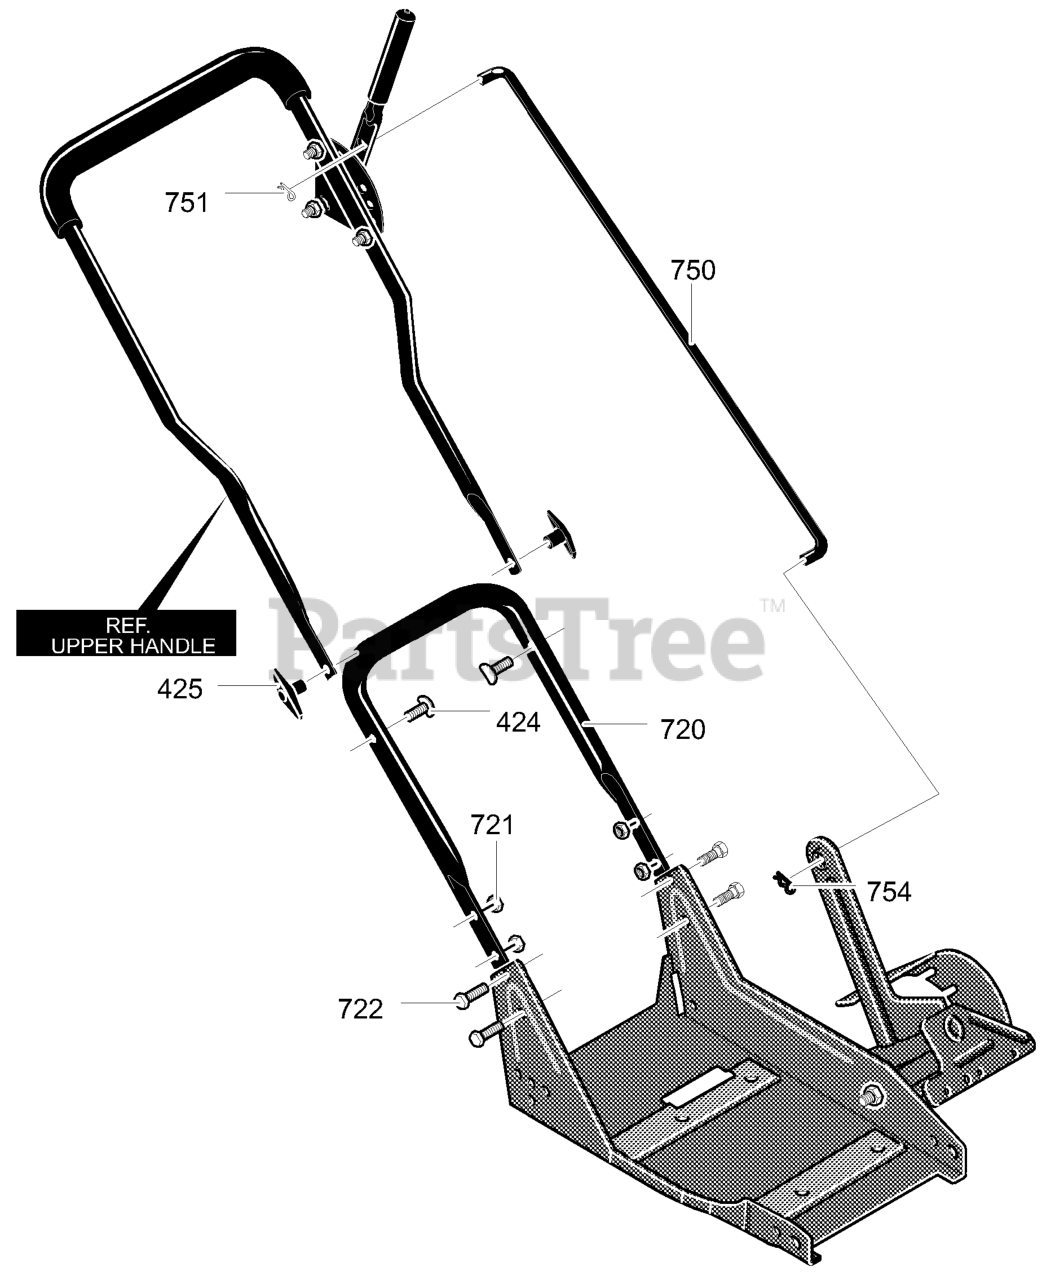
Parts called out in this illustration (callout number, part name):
424	Bolt, 5/16-18x1.75
425	Knob, Wing 5/16-18
720	Lower Handle
721	Nut, 5/16-18
722	Screw, 5/16-18 x 0.63
750	Control Rod
751	Hair Pin
754	Hair Pin
